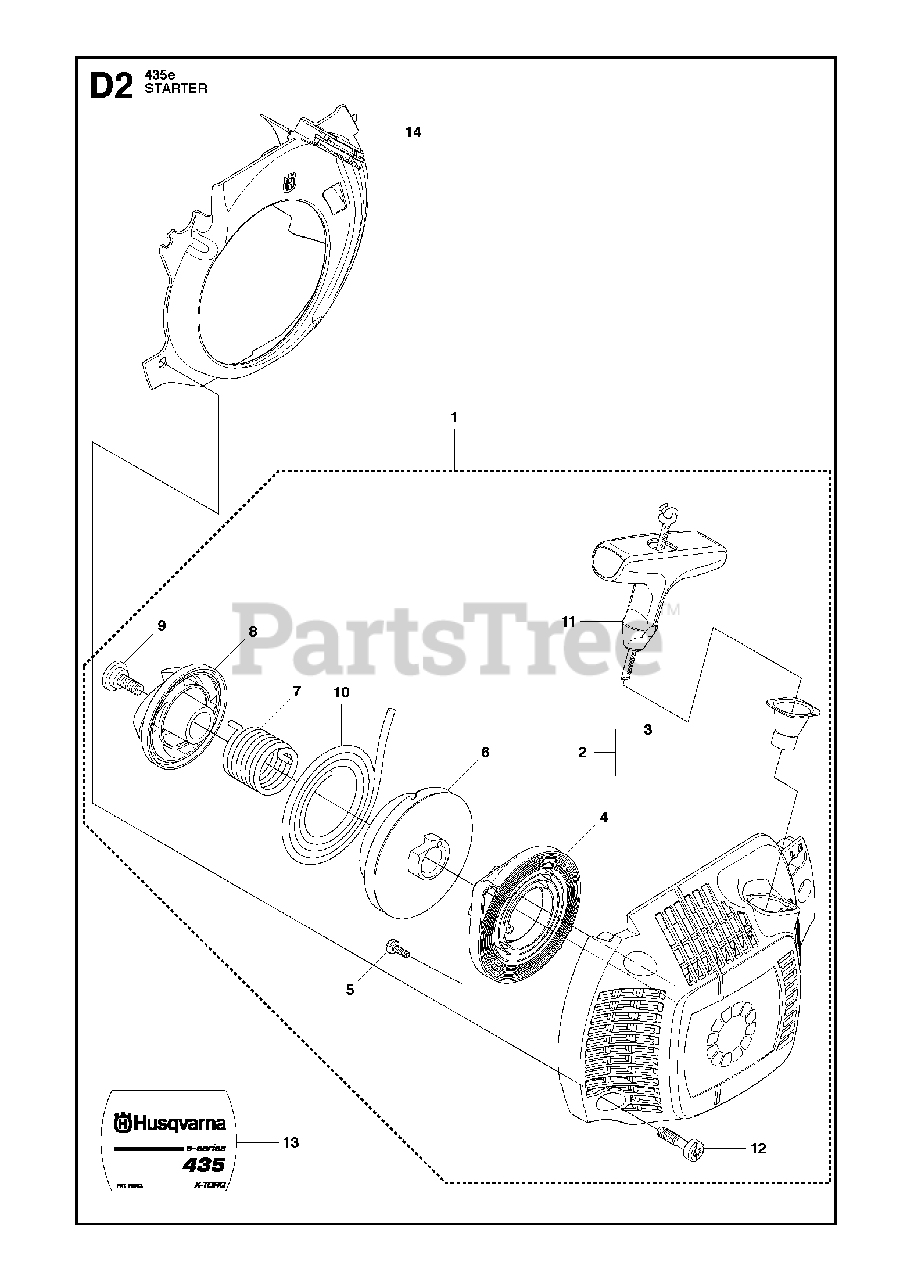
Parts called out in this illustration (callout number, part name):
1	STARTER ASSY
2	STARTER HOUSING
3	SLEEVE
4	SPRING CASSETTE ASSY
5	SCREW
6	STARTER PULLEY
7	SPRING
8	DRIVER
9	SCREW
10	STARTER ROPE
11	HANDLE
12	SCREW
13	LABEL 435 STARTER
14	COOLING AIR CONDUCTOR
